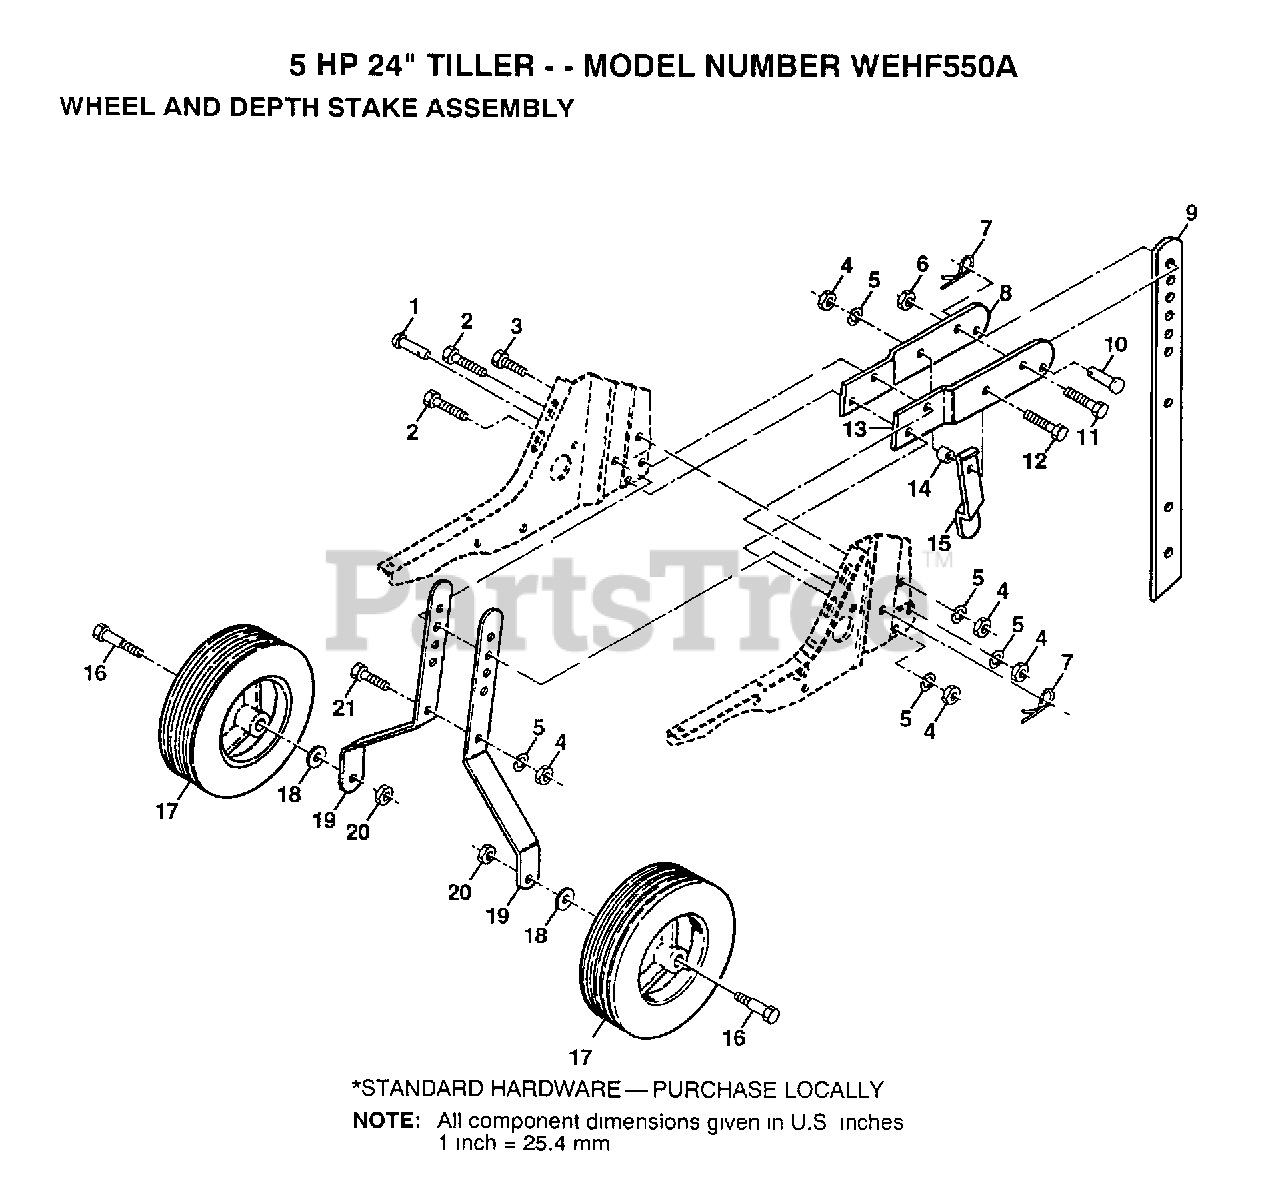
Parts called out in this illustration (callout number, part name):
1	DRILLED RIVET RT
3	BOLT
4	NUT.HEX.5/16-18
5	LOCKWASHER
6	GRIPCO NUT
7	SPRING.RETAINER
11	BOLT.3/8-24X1-1/2
12	BOLT.HEX.5/16-1.5
14	WASHER
15	STAKE SPRING TI
16	BOLT SHOULDER
17	WHEEL.8X1.75.YELL
18	WASHER
